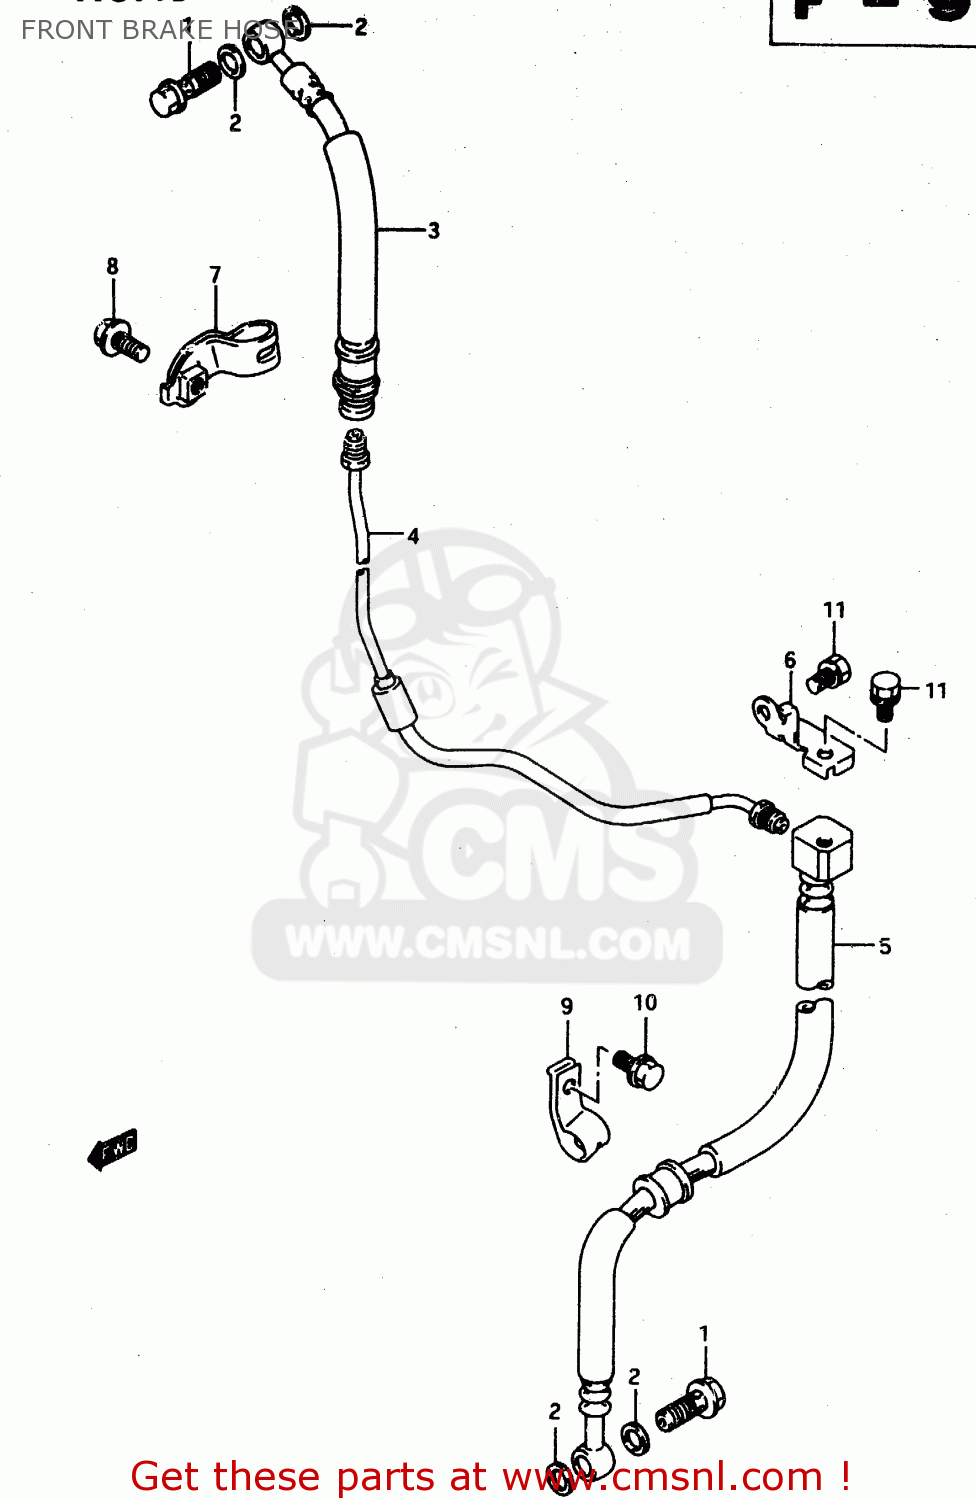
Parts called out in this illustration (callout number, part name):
1	BOLT UNION
2	WASHER(10X15X1.5)
3	HOSE COMP,FRONT BRAKE
4	PIPE,FRONT BRAKE
5	HOSE COMP,FRONT BRAKE
6	BRACKET,FRONT BRAKE HOSE
7	CLAMP COMP,FRONT BRAKE HOLDER
8	BOLT
9	CLAMP,FR BRAKE HOSE NO.2
10	BOLT
11	BOLT
